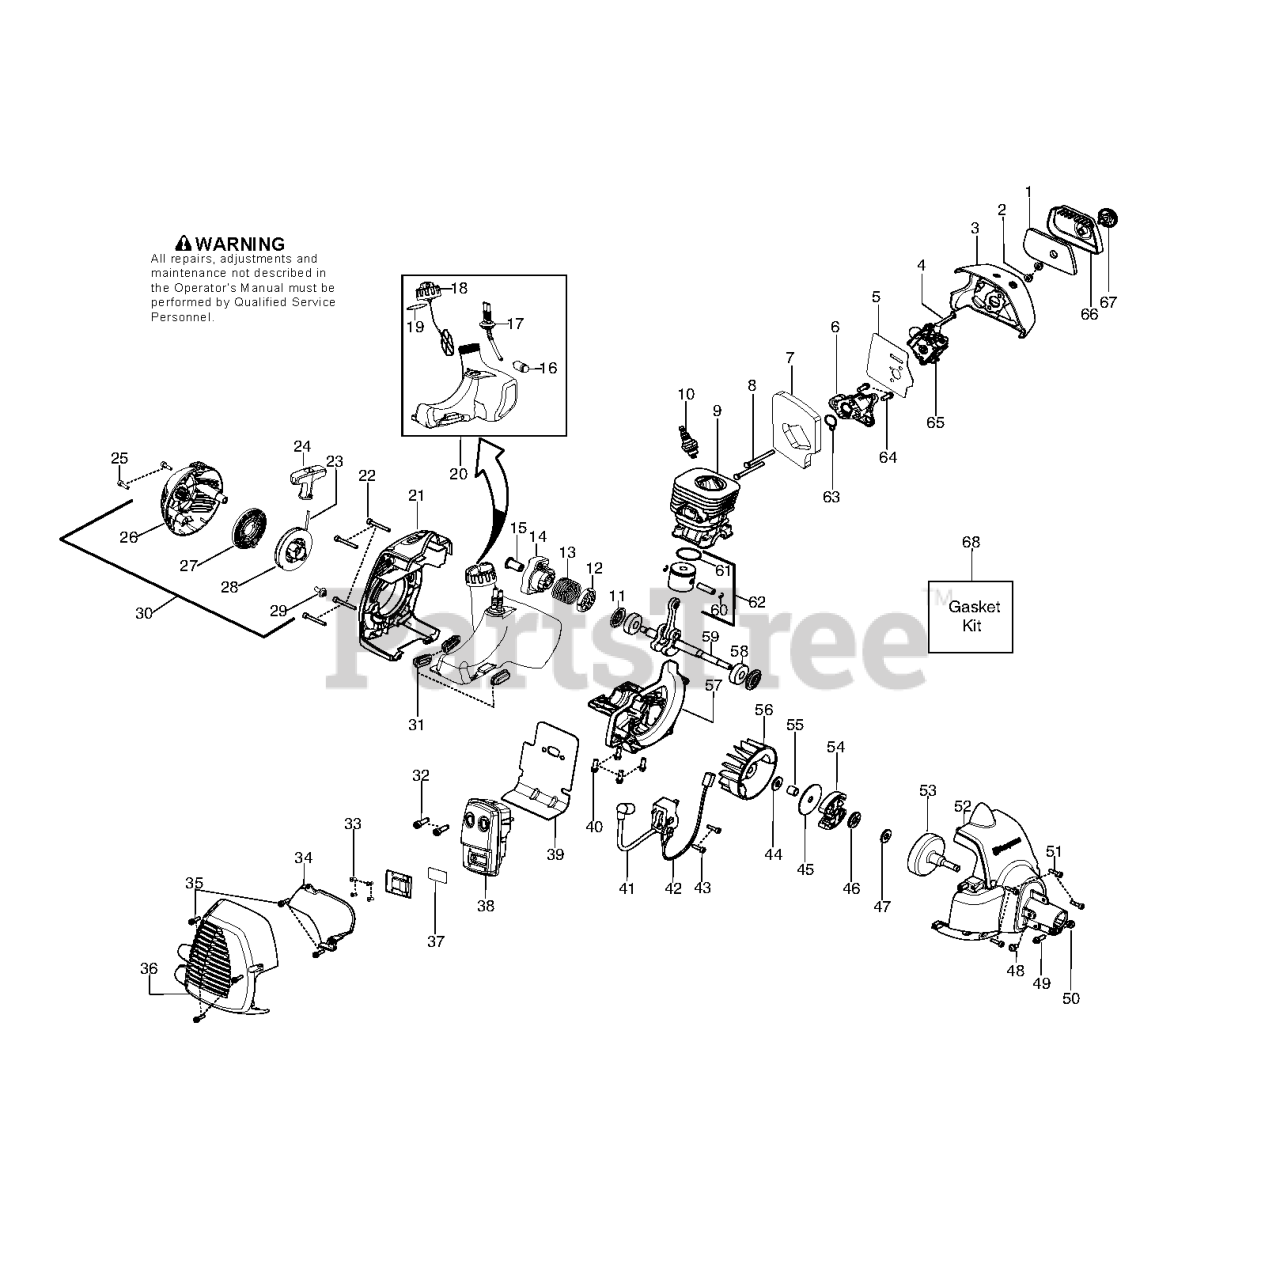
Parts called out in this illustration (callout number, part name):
1	FILTER AIRBOX
3	RP_AIR BOX
4	CHOKE LEVER
5	KIT GASKET CARB
6	CARB ADAPTOR
7	KIT GASKET 28CC
8	BOLT CARB ADAPTOR
9	CYLINDER
10	Plug - Spark (RCJ-8Y)
11	KIT SEAL CRANKSHAFT
12	WASHER STARTER
13	SPRING STARTER CUP
14	ASSY STARTER CUP
15	COUPLING STARTER
16	FUEL PICK-UP ASSY
17	KIT FUEL LINE
18	ASSY-CAP W/RETAINER
19	KIT GASKET 28CC
20	ASSY FUEL TANK HVA
21	REAR SHROUD
24	STARTER HANDLE GRAY
25	SCREW M5-0.8X30MM
26	STARTER HOUSING
27	%KIT STARTER SPRING
28	KIT STARTER PULLEY
30	ASSY-STARTER HSG.
31	ISOLATOR FUEL TANK
32	BOLT MUFFLER
33	SCREW-10-16 X 1/2 HI-LO
34	SHIELD HEAT
35	SCREW M4 X 1.75 PT 16MM
36	GUARD-MUFFLER
37	KIT SPARK ARRESTOR SCREEN
38	ASSY-MUFFLER
39	KIT GASKET 28CC
40	SCREW-M5-0.8 X 25MM(TAP)
41	IGNITION MODULE MBU-7
42	ASSY MODULE LEAD WIRE
43	SCREW M4 X .70 TT 16MM
44	WASHER CLUTCH
45	WASHER-CLUTCH
46	BEARING THRUST
47	WASHER THRUST
50	LOCKNUT-HEX 10-24
51	SCREW M4 X .70 TT 16MM
52	FAN HSG ASSY
53	ASSY-CLUTCH DRUM
54	%KIT CLUTCH ASSY
55	SPACER FLYWHEEL
57	CRANKCASE CASTING
58	BEARING RADIAL BALL (6201)
59	KIT CRANKSHAFT ASSY
60	WRIST PIN RET.
61	RING PISTON
62	KIT PISTON 28CC TRIMMER
63	KIT GASKET 28CC
64	SCREW-M5-0.8 X 25MM(TAP)
66	COVER-AIR BOX
67	KNOB ASSY AIRBOX COVER
68	KIT GASKET 28CC
